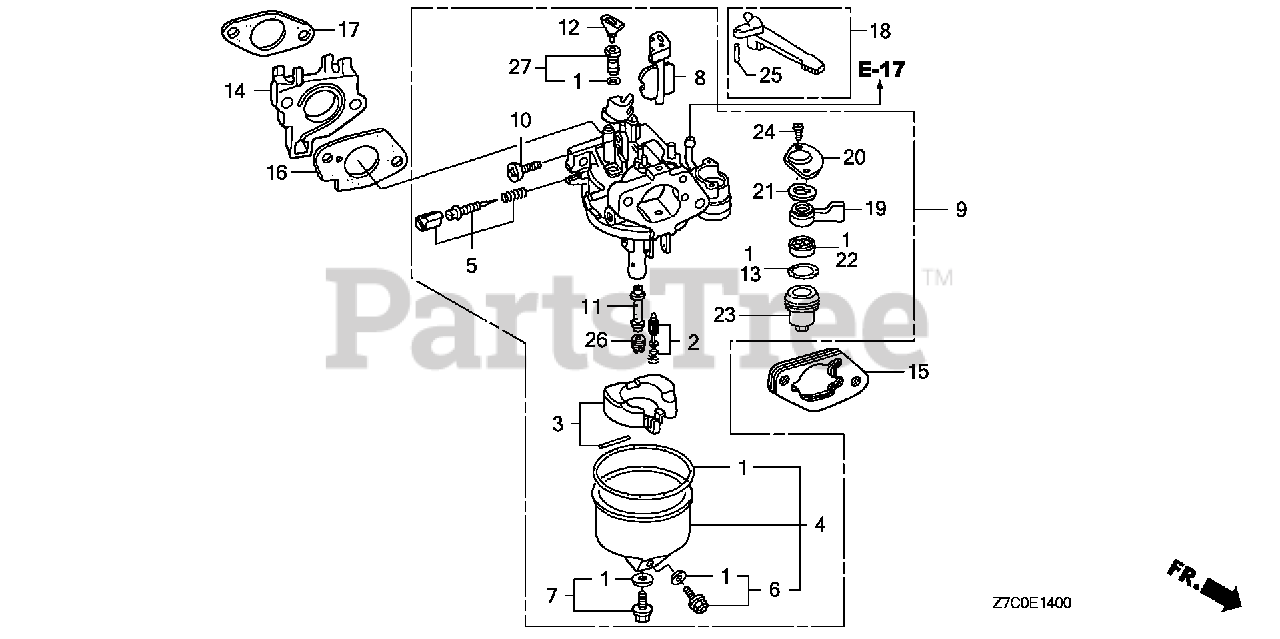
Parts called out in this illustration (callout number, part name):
1	GASKET SET (INCLUDES 16173-001-004)
2	VALVE SET, FLOAT
4	CHAMBER SET, FLOAT
5	SCREW SET, PILOT
6	SCREW SET, DRAIN
7	SCREW SET
9	CARBURETOR ASSY. (BE70M A)
10	SCREW, THROTTLE STOP
11	NOZZLE, MAIN
12	COLLAR, SETTING
13	GASKET, FUEL STRAINER CUP
14	INSULATOR, CARBURETOR
15	SPACER, CARBURETOR
16	GASKET, CARBURETOR
17	GASKET, INSULATOR
18	LEVER, CHOKE (STD)
19	LEVER, PETCOCK
20	PLATE, LEVER SETTING
21	SPRING, PETCOCK LEVER
22	GASKET, PETCOCK
23	CUP, FUEL STRAINER
24	SCREW, PAN (3X6)
25	PIN, SPRING (2X12)
26	JET, MAIN (#88)
26	JET, MAIN (#90)
26	JET, MAIN (#92)
27	JET SET, PILOT (#40)
